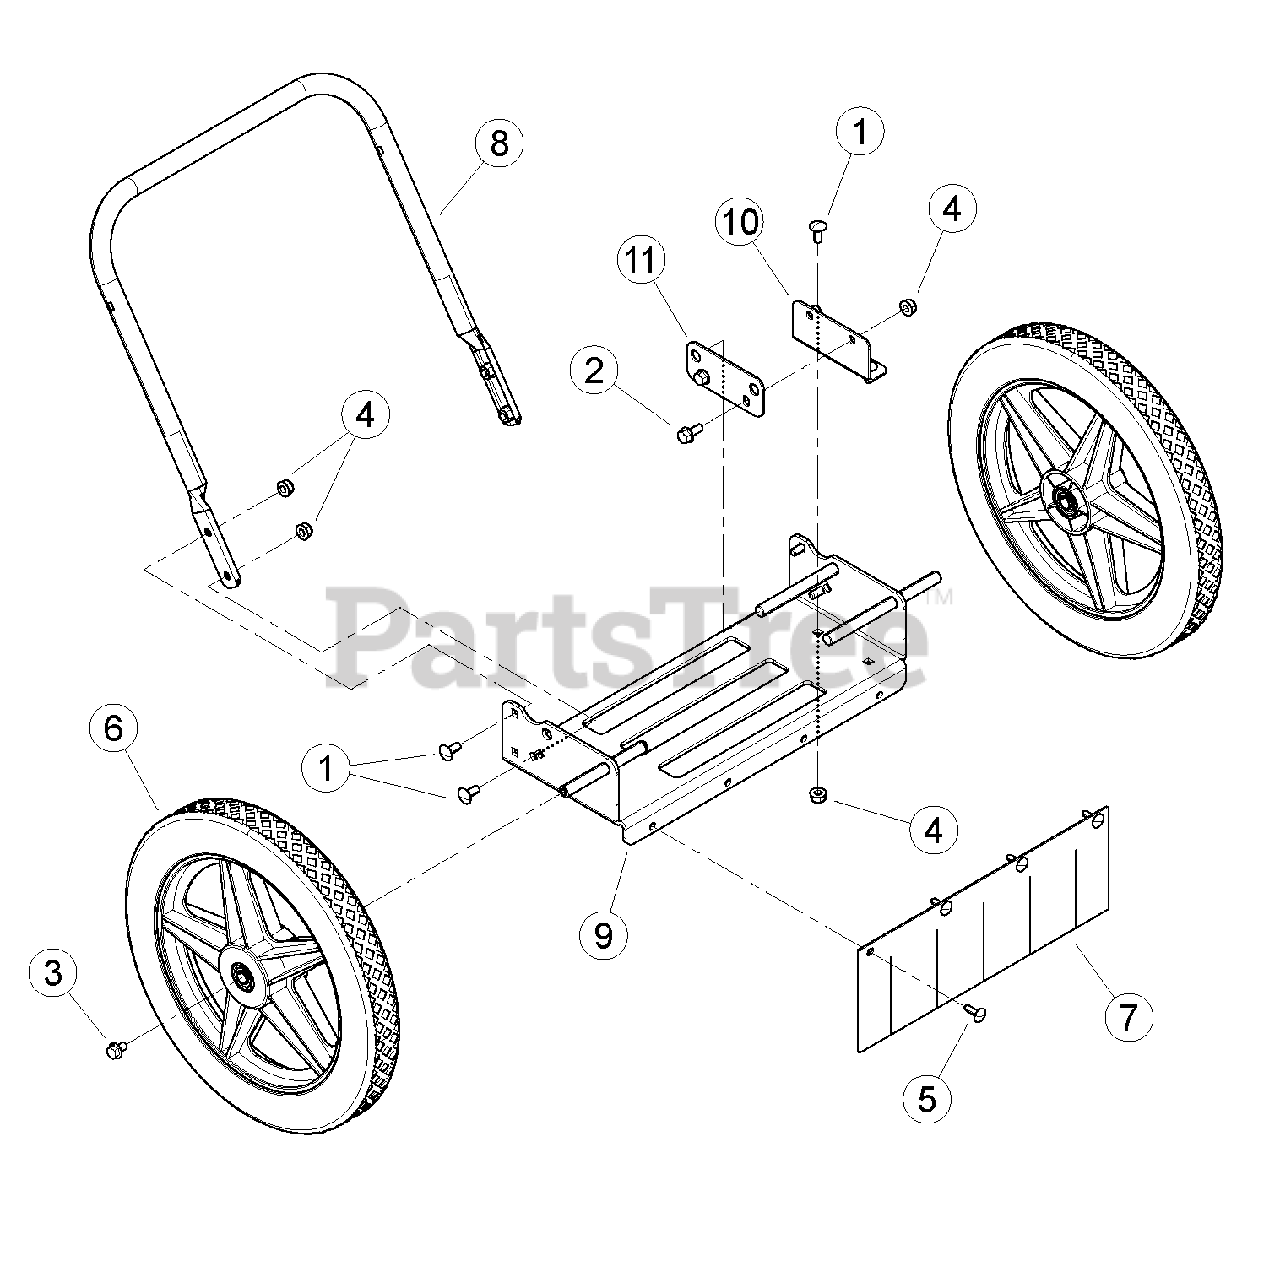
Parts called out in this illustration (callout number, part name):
1	BOLT, 5/16-18 X 3/4 SN GR5 CRG
2	BOLT, 5/16 X 3/4 FLANGE NC
3	BOLT, 5/16-18 X 1/2 G5 HH SERRATED FLANGE
4	NUT, 5/16-18 NYLOCK FLANGE
5	RIVET, PLASTIC .28 X 1"
6	WHEEL, TRIMMER 15 X 1.75
7	FLAP, TRIMMER
8	HANDLE BAR, LOWER TRIMMER PAINTED
9	WELDMENT, AXLE HWT
10	BRACKET, AXLE SUPPORT HWT
11	PLATE, AXLE SUPPORT HWT
